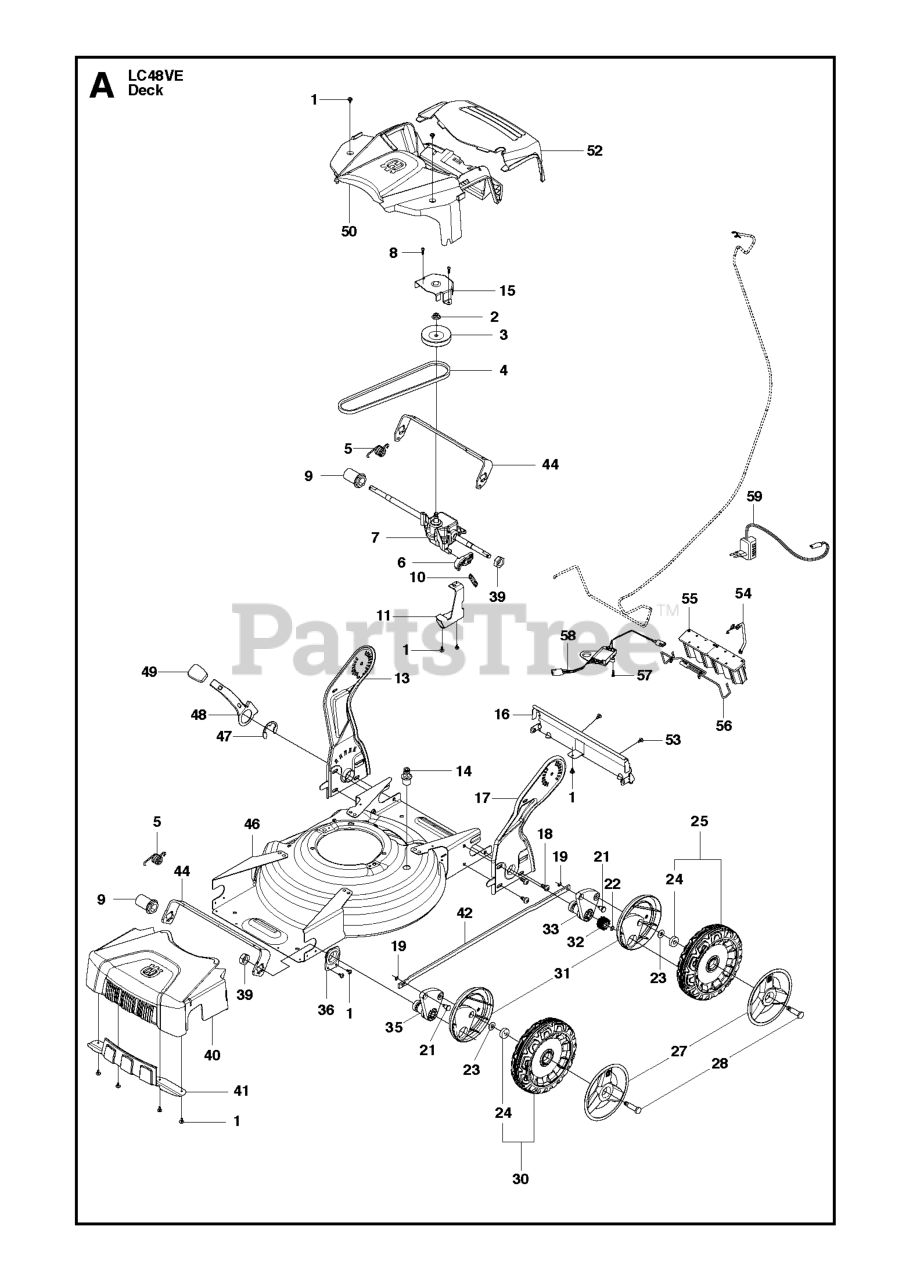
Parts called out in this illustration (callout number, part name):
1	SCREW ITXPANTT M5X10 ZPB (A00
4	BELT WRAPPED V-BELT Z 29.5
8	SCREW ITXPANT T50X16 ZN/FE (A
19	FASTENER
24	BALL BEARING
46	CHASSIS 48S A009 PAINTED
53	SCREW ITXPANTT M5X10 ZPB (A00
